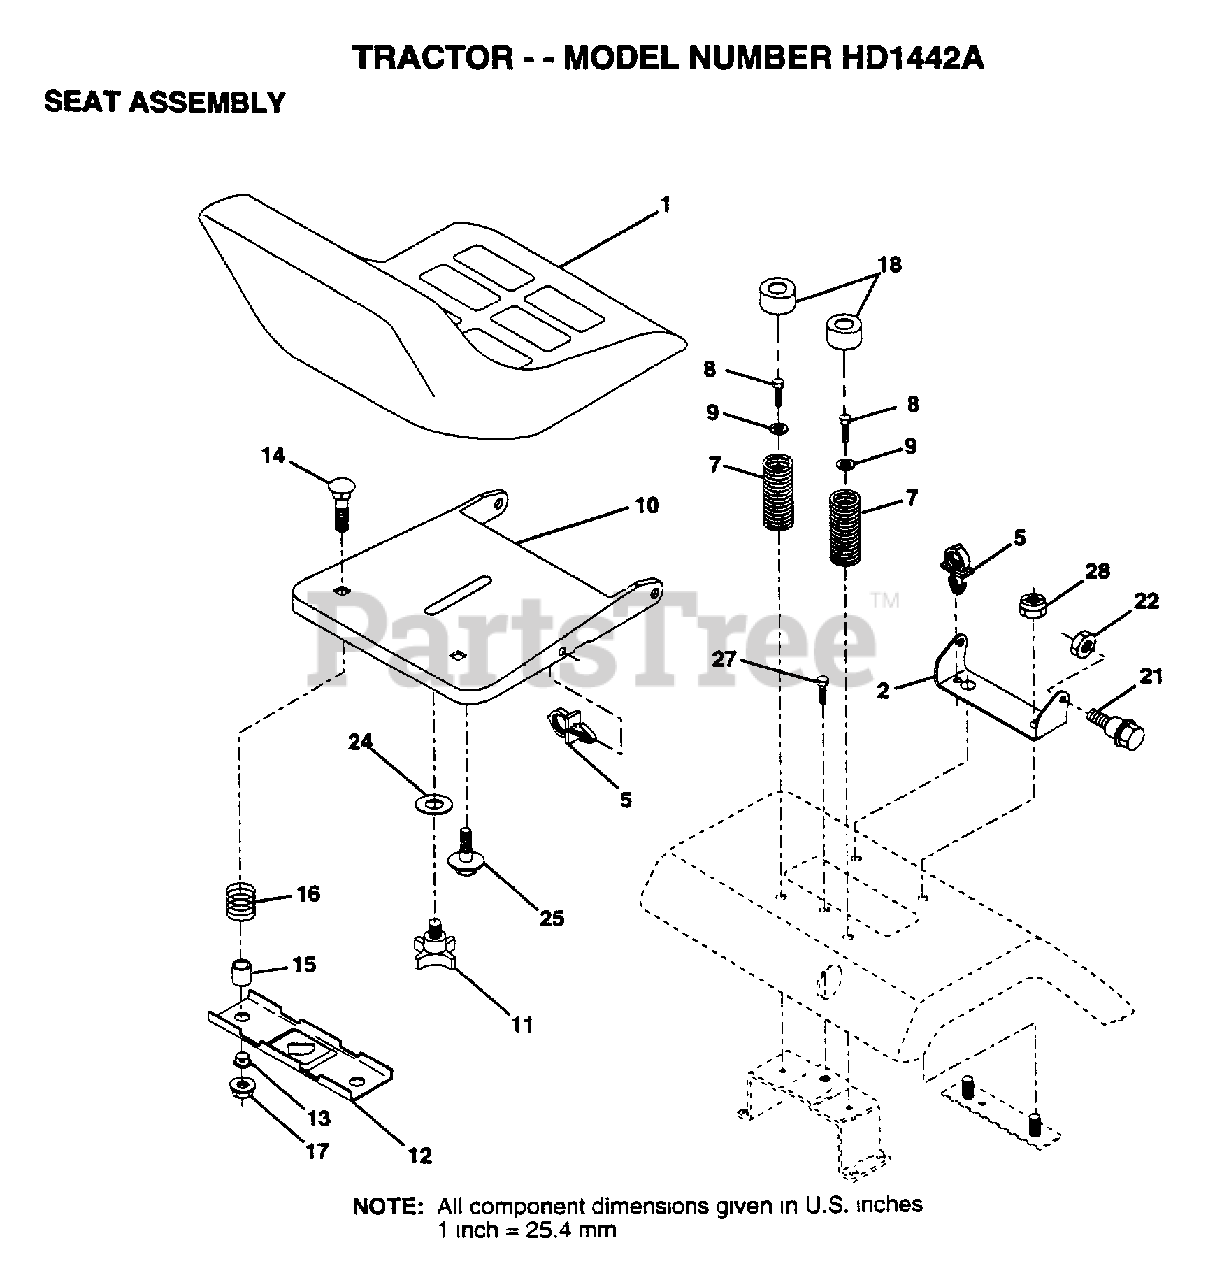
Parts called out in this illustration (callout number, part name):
1	SEAT.2400/1416.BK
2	BRACKET PVT SEAT
5	CLIP.PUSH-IN.HING
7	SPRING COMPRESSIO
8	SCREW LT
9	WASHER
11	"KNOB 1/2"" YT"
12	BRKT SWITCH
13	BUSHING
15	SPLIT SPACER
16	SPRING
18	CAP SPRING
21	BOLT.SHLD.5/16-18
22	NUT
24	WASHER
25	"BOLT,SHOULDER"
27	SCREW LT
